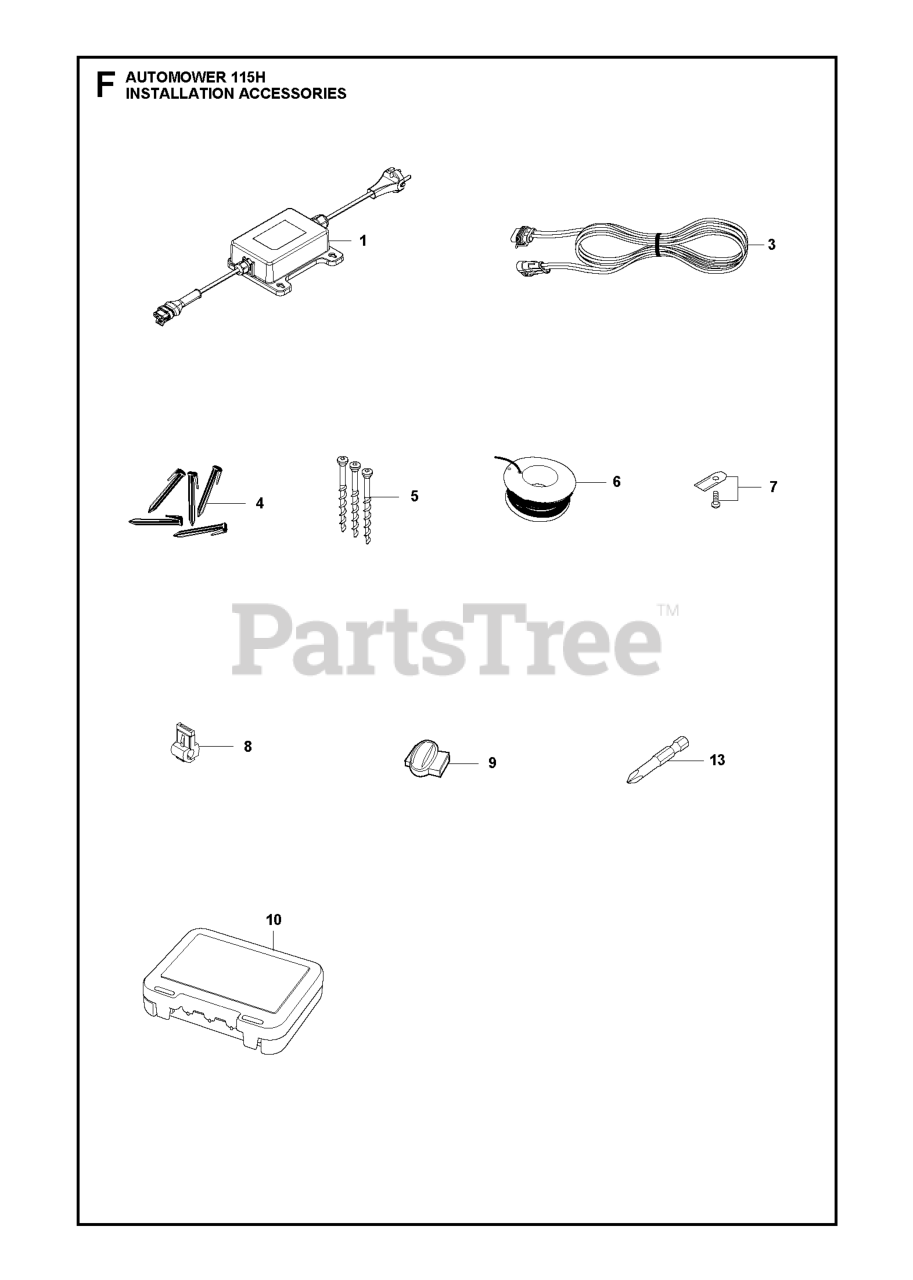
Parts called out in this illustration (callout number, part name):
3	CABLE ASSY LOW VOLTAGE CABLE
4	STAPLE 100 PCS, BLISTER
4	STAPLE 100 PCS
5	SCREW 3 PCS, BLISTER PACK
6	WIRE 50M STANDARD Ø2.7MM,BLIST
6	WIRE BOUNDARY 150M
6	WIRE 150M, BLISTER
7	HUS BLADE SET 9 PCS
7	HUS BLADE SET 45 PCS
7	HUS BLADE SET 300 PCS
8	CONNECTOR 5 PCS, BLISTER
8	BRAKER
8	CONNECTOR 100 PCS
9	COUPLER SPLICER, 5 PCS,
9	SPLICE KIT
9	COUPLER SPLICER, 100 PCS
10	CONNECTOR PROTECTION BOX
13	WRENCH BITS CHANGING ROBOTIC B
